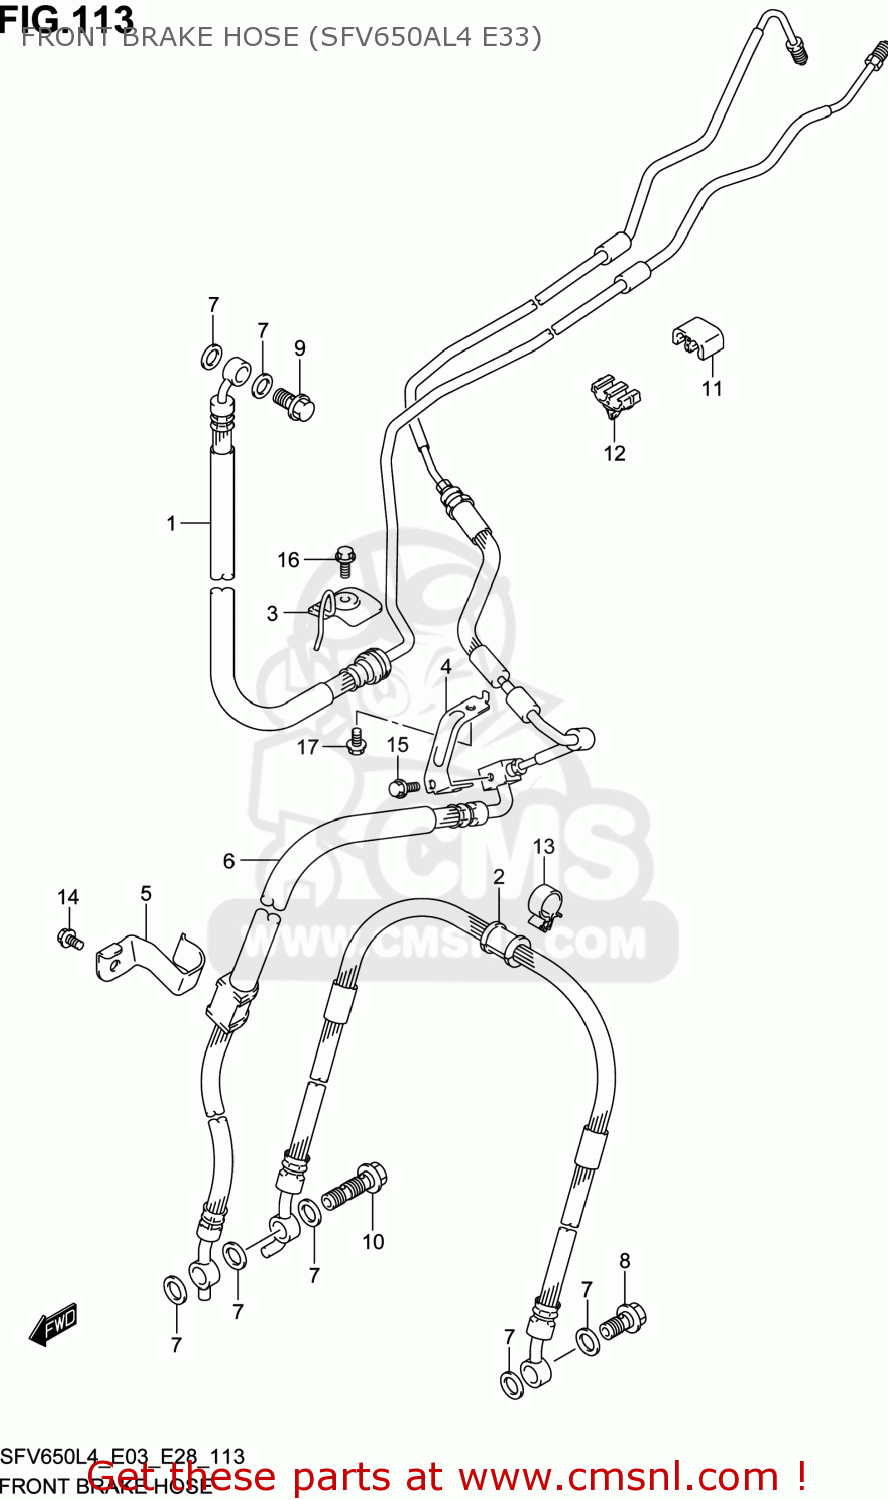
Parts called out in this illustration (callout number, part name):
1	HOSE ASSY,FR BRAKE NO.1
2	HOSE,FR BRAKE NO.2
3	CLAMP,FR BRAKE HOSE ASSY NO.1
4	CLAMP,FR BRAKE HOSE ASSY NO.2
5	CLAMP,FR BRAKE HOSE NO.2
6	HOSE ASSY,FR BRAKE NO.2
7	WASHER(10X15X1.5)
8	BOLT UNION
9	BOLT UNION
10	BOLT UNION
11	CLAMP
12	CLAMP
13	CLAMP
14	BOLT
15	BOLT
16	BOLT
17	BOLT
